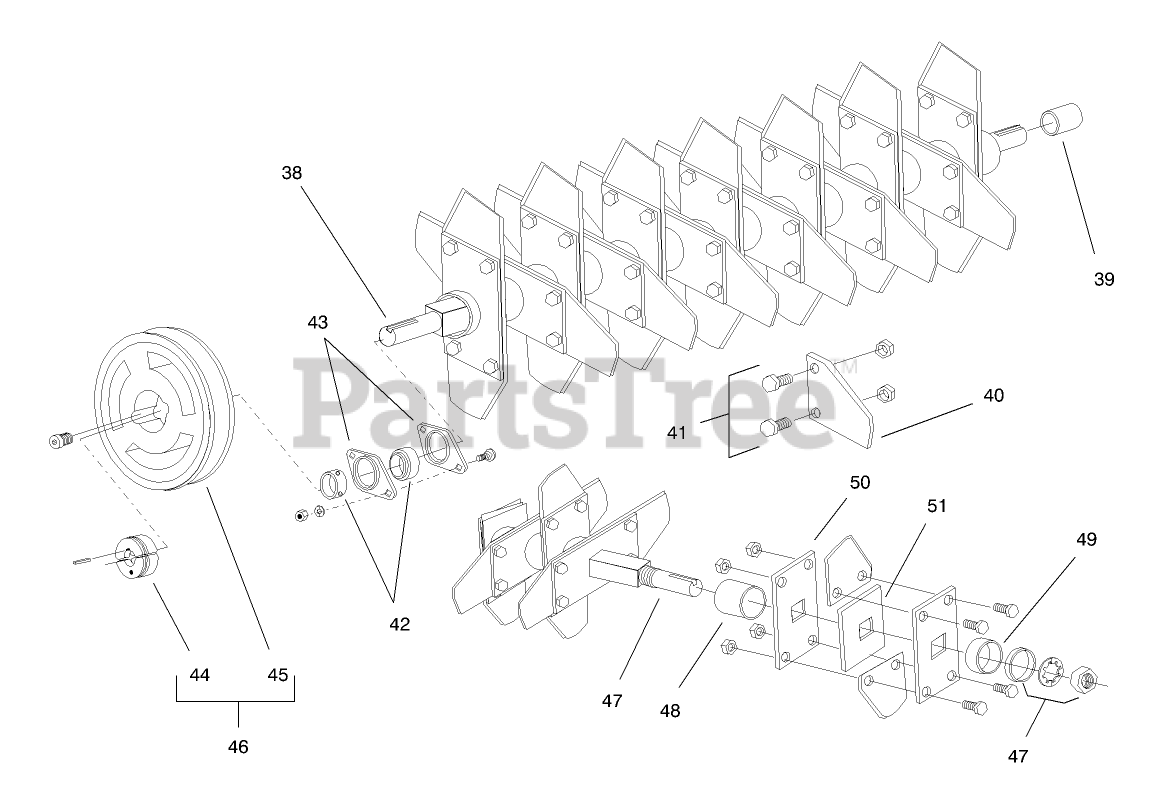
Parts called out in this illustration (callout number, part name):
38	ASSEMBLY - REEL
40	BLADE SET
41	KIT - BOLT
42	BEARING
43	KIT - STAMPING
44	BUSHING
45	V-PULLEY
46	V-PULLEY
47	SHAFT
48	SPACER
49	END RING
50	PLATE
51	PLATE
